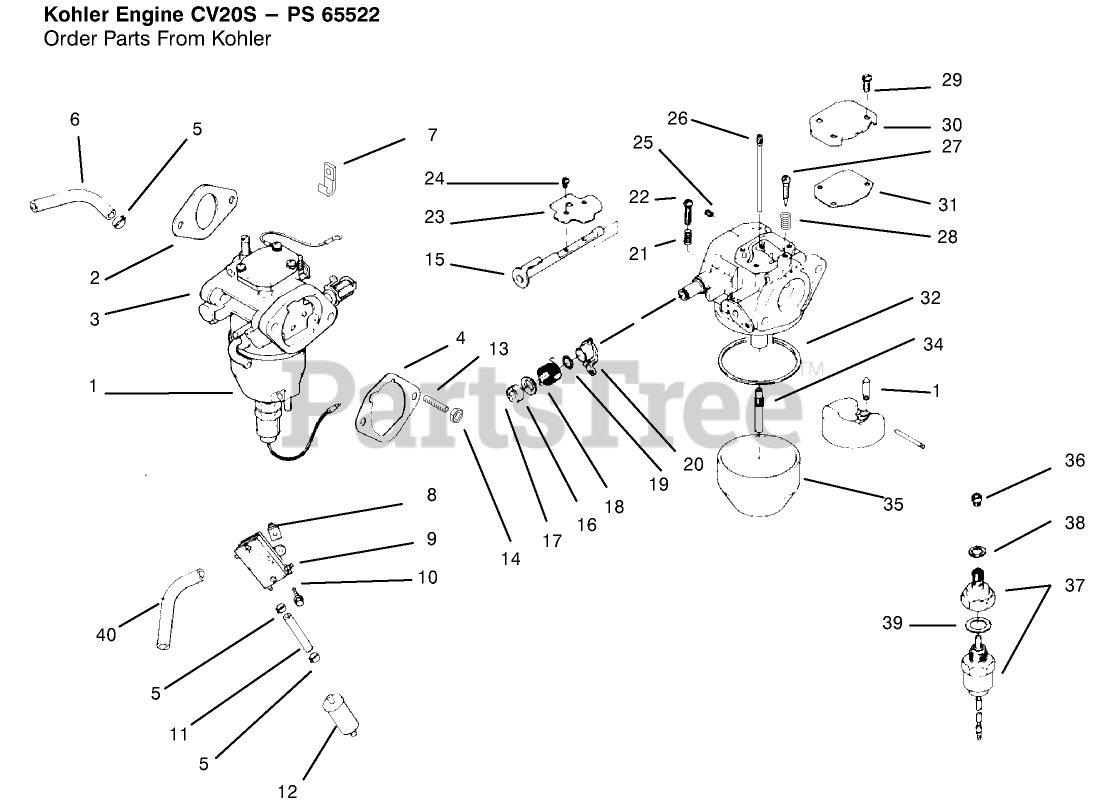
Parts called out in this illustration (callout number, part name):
1	Kit-Carburetor/w Gasket (Incl. Ref.#2-4)
2	Kit-Carburetor
3	Carburetor (Ref. Only)(Inc. Ref. 15-39)
4	Gasket-A/C Base
5	Clamp
6	Line-Fuel 12"
7	Clamp
8	Nut
9	Pump-Fuel
10	Screw
11	Line-Fuel
12	Filter-Fuel
13	Stud
14	Nut
15	Shaft-Choke
16	Washer
17	Collar-Coke
18	Spring-Choke Return
19	Ring-Choke Lever
20	Lever-Choke
21	Sprin-Throttle Screw
22	Screw-Throttle Adjust
23	Plate-Choke
24	Screw
25	Jet-Air Bleed
26	Jet-Slow
27	Screw
28	Spring-idler Screw
29	Screw
30	Cover-Passage
31	Gasket-PassageCover
32	Gasket-FloatChamber
34	Nozzle-Main
35	Chamber-Float
36	Jet-Main
37	Kit-Solenoid Valve (Incl. Ref. #38-39)
38	Gasket-ChamberScrew
39	Gasket-Solenoid
40	Line, fuel
